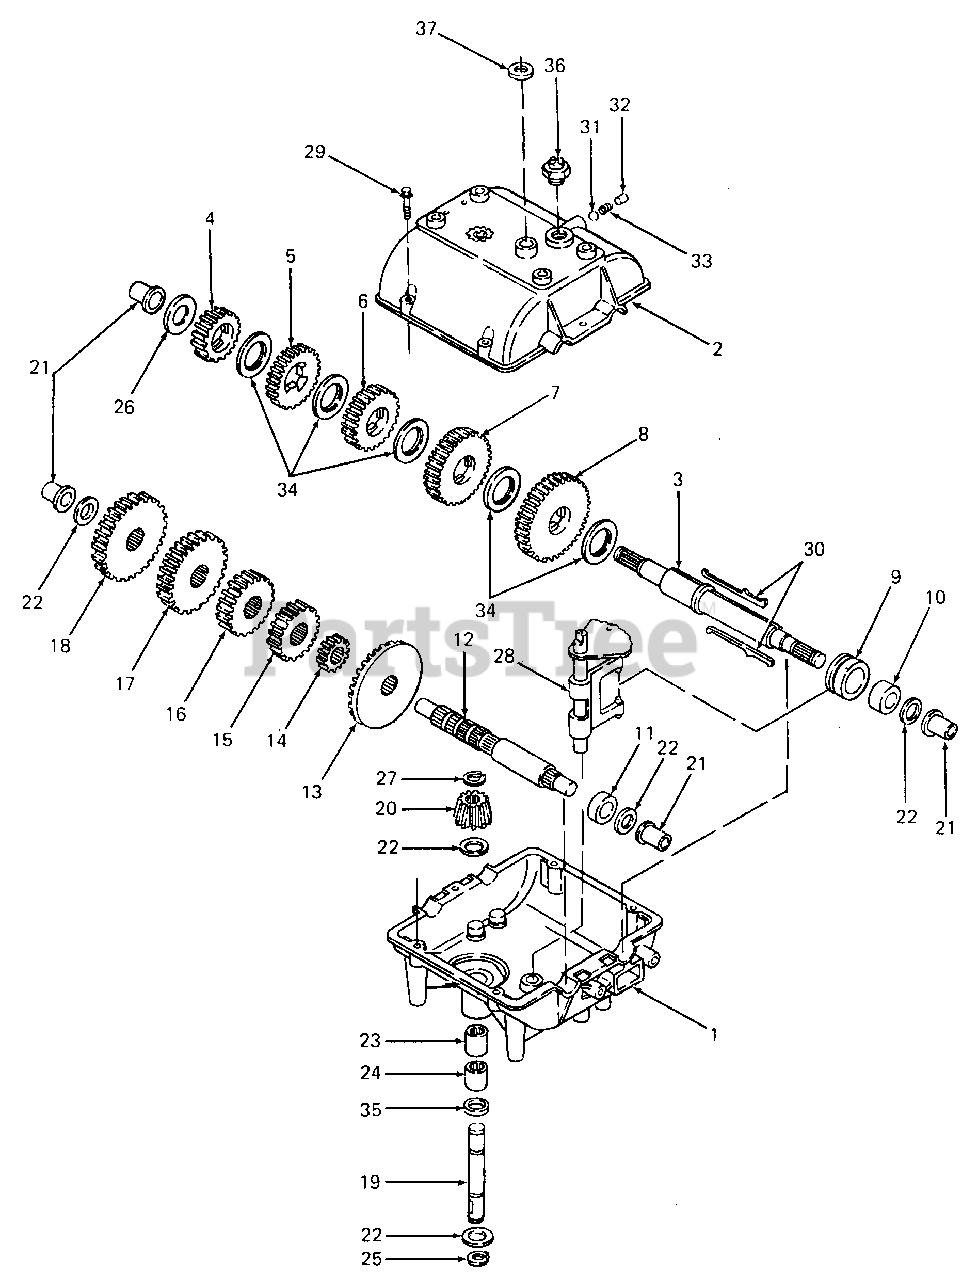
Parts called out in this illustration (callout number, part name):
1	Case, Transmission
2	Cover, Transmission
3	Shaft, Output
4	Gear, Spur (19 Teeth)
5	Gear, Spur (22 Teeth)
6	Gear, Spur (25 Teeth)
7	Gear, Spur (30 Teeth)
8	Gear, Spur (37 Teeth)
9	Collar, Shift
10	Spacer, Output Shaft
11	Spacer, Counter Shaft
12	Shaft, Counter
13	Gear, Bevel (42 Teeth)
14	Gear, Spur (12 Teeth)
15	Gear, Spur (20 Teeth)
16	Gear, Spur (25 Teeth)
17	Gear, Spur (28 Teeth)
18	Gear, Spur (31 Teeth)
19	Shaft, Input
20	Pinion, Input Bevel
21	Bushing, Flanged
22	Washer, Thrust
23	Bearing, Needle
24	Bearing, Needle
25	Ring, Retaining
27	Ring, Retaining
28	Rod & Fork Assy, Shift
29	Screw, Flanged Hex Hd, 1/4-20 X 1/25 Lg
30	Key
31	Ball, Steel, 5/16
32	Screw, Set, 3/8-16 X 3/8 Lg
34	Washer, Thrust
36	Switch, Neutral Start
37	Seal, Square Cut
